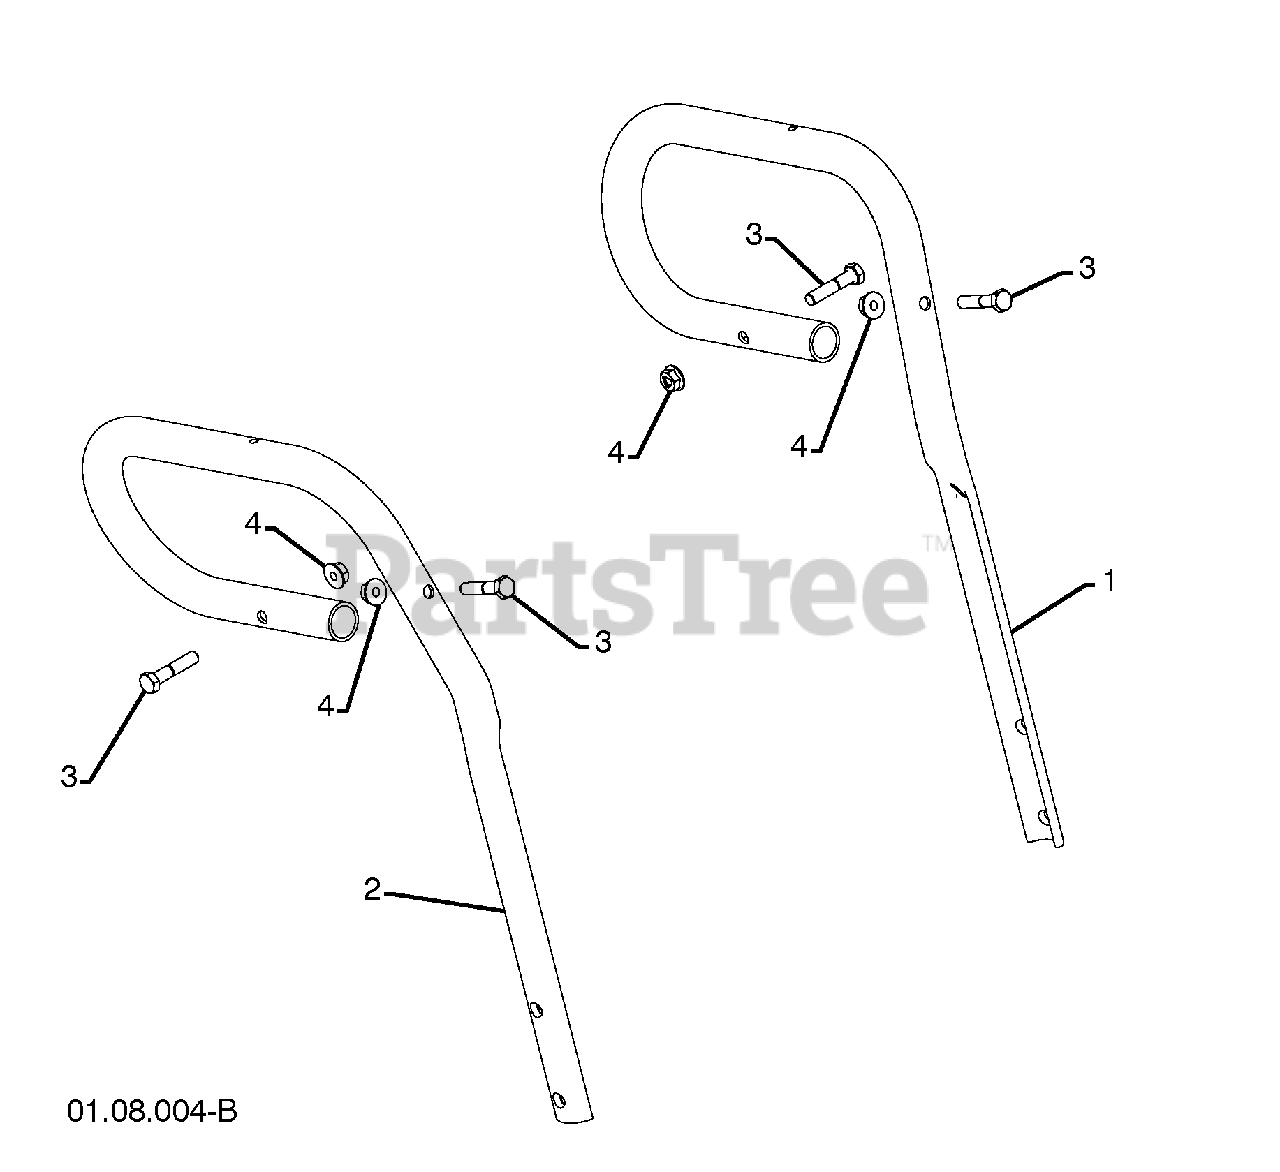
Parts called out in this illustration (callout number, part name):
1	LOOP HANDLE LH
2	LOOP HANDLE RH
3	SCREW 5/16-18 X 1.50
4	NUT 5/16-18
